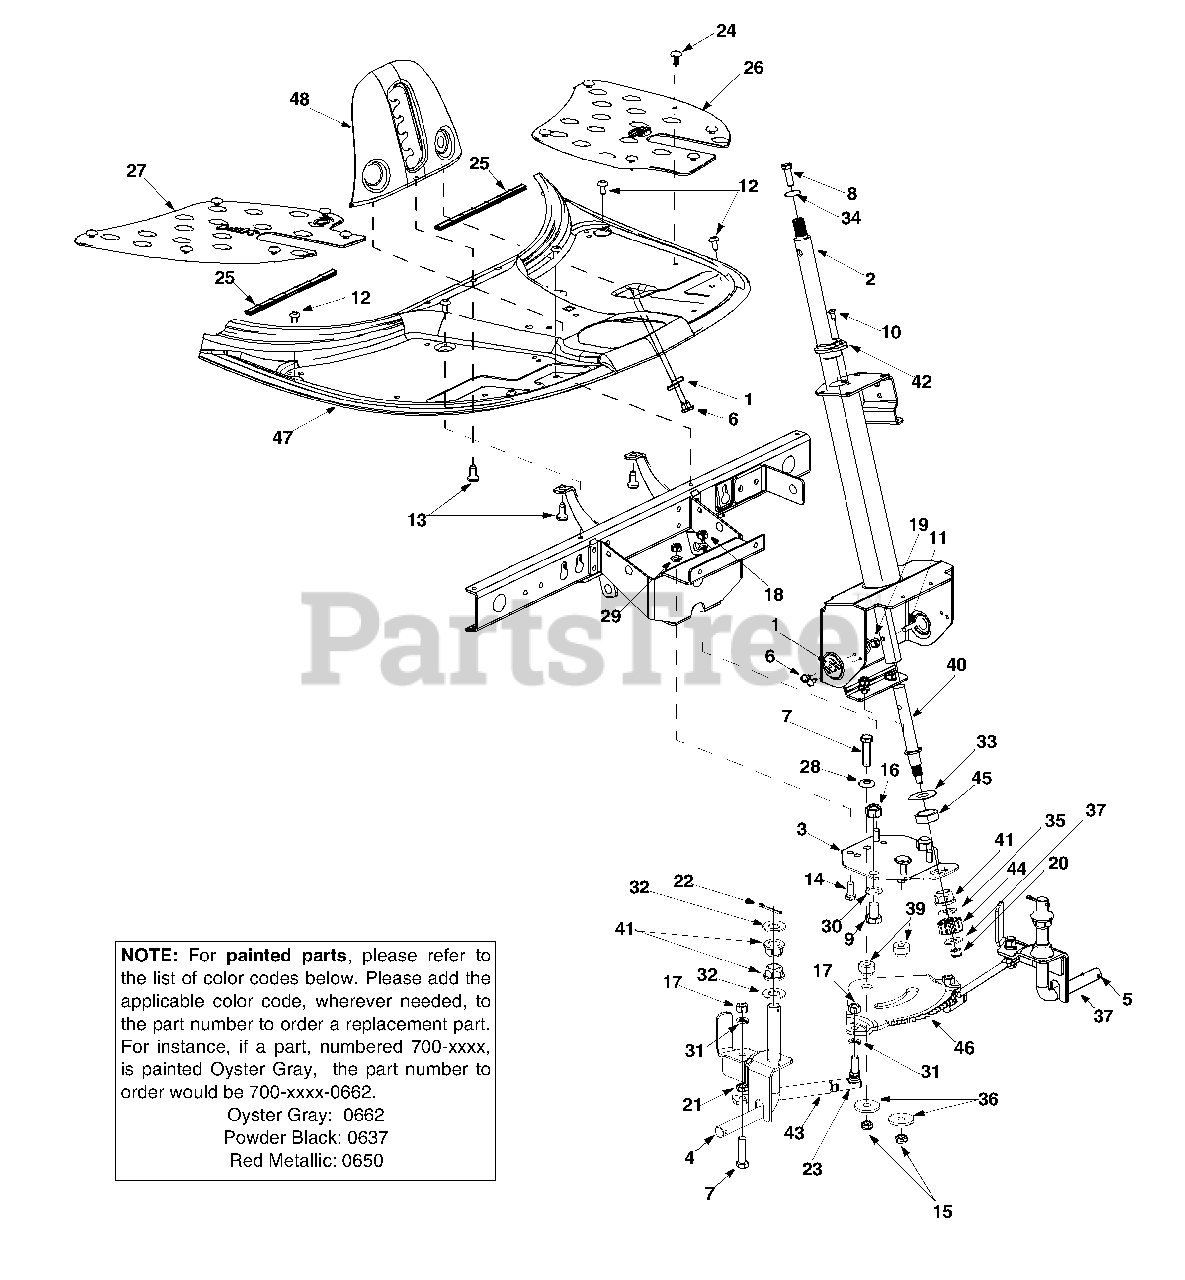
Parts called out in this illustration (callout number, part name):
1	Switch Plate
4	Front Axle Assembly: RH
5	Front Axle Assembly: LH
6	Hex Screw AB
7	Hex Screw 3/8-24 x 1.5" Gr.5 Sp.
8	Lock Screw 5/16-18 x 1.0" Gr.5
9	Hex Screw 1/2-13 x 0.75"
10	Oval C-Sunk Screw #10-16 x 0.625"
11	Hex Screw 1/4-20 x 1.25 Gr.5 Sp.
12	AB Screw 1/4-14 x 0.625"
13	Self-Tapping Screw 5/16-18 x 0.75"
14	Hex Screw 5/16-18 x 0.75"
15	Lock Nut 3/8-24
16	Hex Nut 1/2-13
18	Hex Nut
19	Lock Nut 1/4-20
23	Ball Joint
24	Ratchet Clip
26	Floor Pad: LH
27	Floor Pad: RH
29	Lock Washer
34	Beleville Washer
39	Spacer
40	Steering Adapter
41	Hex Flange Bearing
42	Bearing: Steering Column
44	Pinion Gear
45	Spacer
46	Gear: Steering Segment
